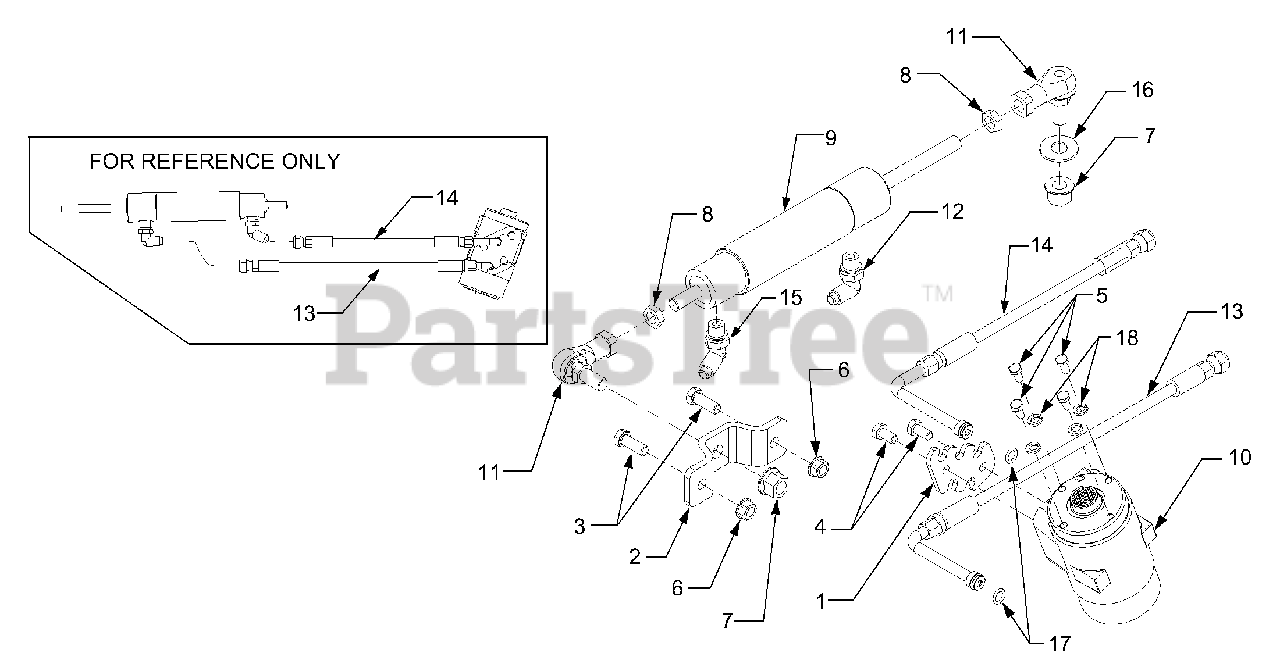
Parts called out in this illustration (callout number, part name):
1	Plate, Steering Pump Port
2	Bracket, Cylinder Mounting
3	Screw, Hex Cap 3/8-16 x 1.0 GR5
4	Screw, Hex Cap M8-1.25 x 16MM GR5
5	Screw, Hex Cap, M6 x 14MM
6	Nut, Hex Flange Lock, 3/8-16
7	Nut, Hex Flange Lock, M12 x 1.75
8	Nut, Hex, M12 x 1.75 RH
9	Cylinder, Steering
10	Pump, Hydraulic Steering
11	Ball Joint, 12MM x 1.75 RH
12	Fitting, 90 Degree Elbow
13	Hose, Front Steering
14	Hose, Rear Steering
15	Fitting, 45 Degree
16	Washer, Flat, .51 x 1.12 x .060
17	O-Ring, .426 x .566 x .070
18	Washer, Lock, 1/4"
